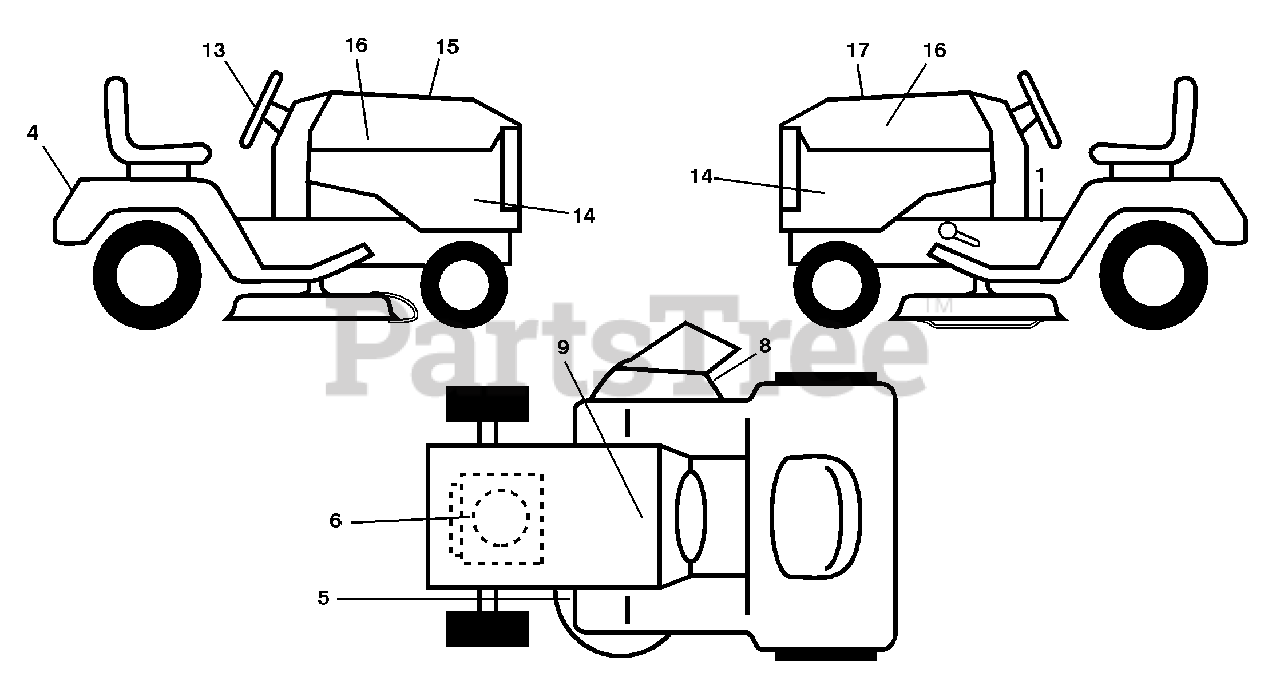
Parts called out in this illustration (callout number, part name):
1	Decal, Operator's
4	Decal, Fender
5	Decal, Caution
6	Decal, Eng. HP
8	Decal, Mower Sch.
9	Decal, Battery Dnge/Poi
13	Decal, Steering Whl
14	Decal, Panel Side
15	Decal, Cust. Resp.
16	Decal, Hood Logo
17	Decal, Replacement
17	Decal, Bypass
17	Pad, Footrest, LH
17	Pad, Footrest, RH
17	Manual, Owner's
